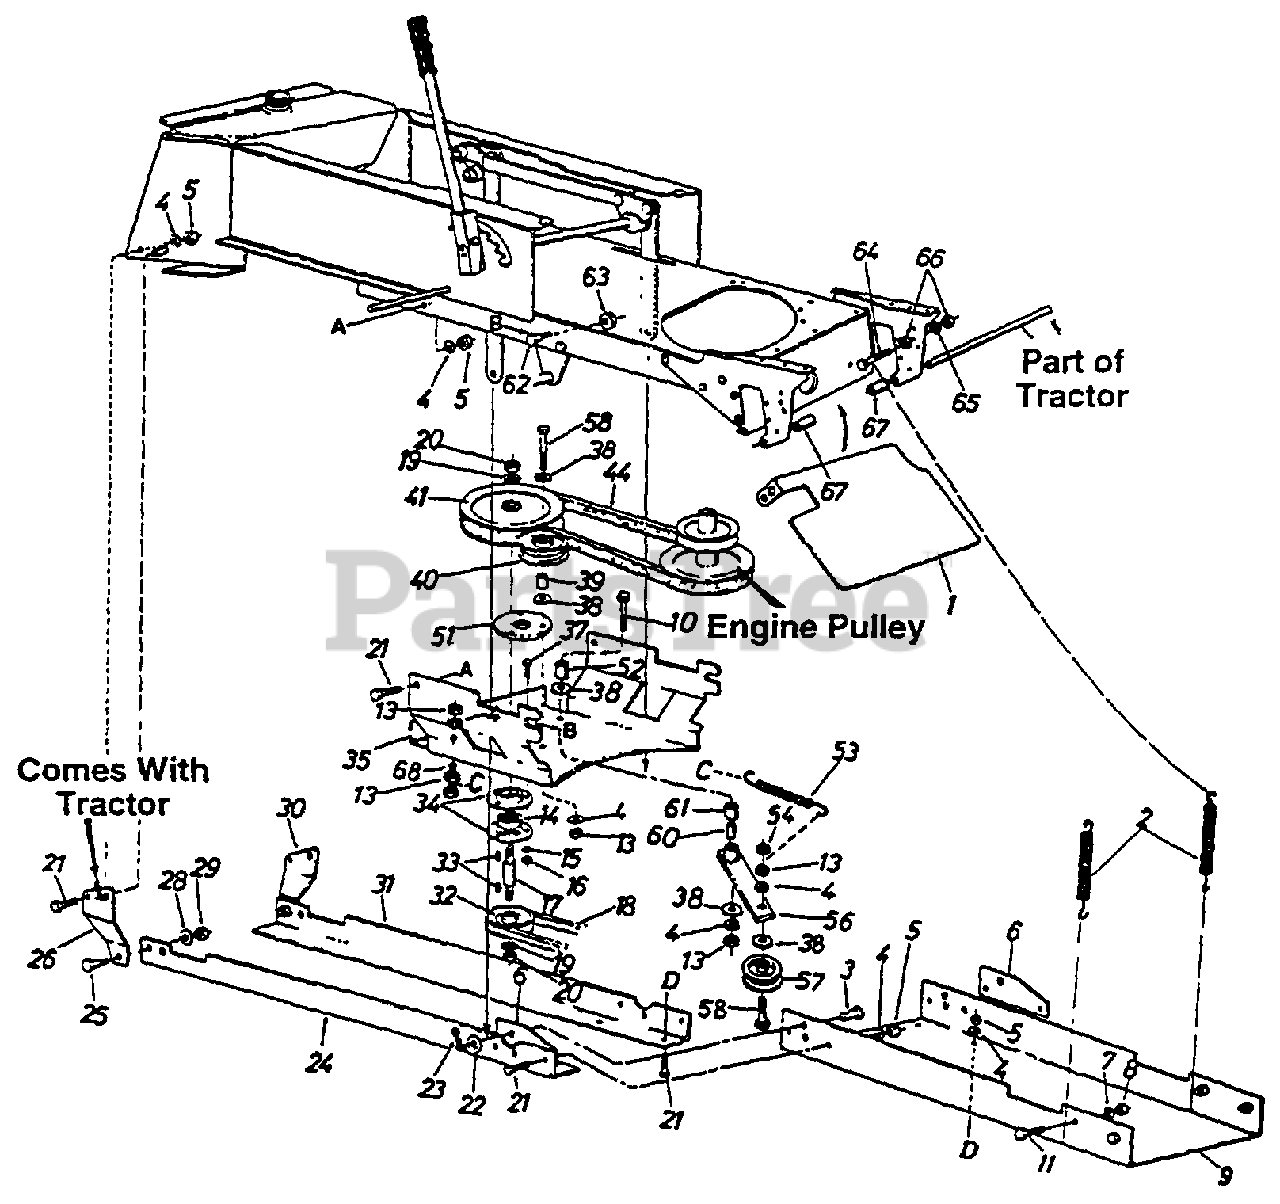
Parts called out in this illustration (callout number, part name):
3	Clevis Pin
4	L-Wash. 3/8" I.D.
5	Hex L-Nut 3/8-24 Thd.
6	Attaching Plate
7	L-Wash. 1/2" I.D.
8	Hex L-Nut 1/2-20 Thd.
11	Hex Bolt 1/2-20 x 1.25" Lg.
13	Hex Jam Nut 3/8-16 Thd.
14	Ball Bearing
15	L-Wash. 5/16" I.D.
16	Hex Nut 5/16-18 Thd.
17	Spindle
18	"V"-Belt
19	L-Wash. 5/8" I.D.
20	Hex Jam Nut 5/8-11 Thd.
21	Hex Bolt 3/8-24 x 1.00" Lg.
22	Flat Washer
23	Internal Cotter Pin
29	Hex Nut 7/16-14 Thd.
30	Rear Hanger Brkt.- L.H.
33	#6 Hi-Pro Key 3/16 x 5/8" Dia.
34	Bearing Housing
35	Supporting Bracket
37	Hex Sems Bolt 5/16-18 x 1"
38	Fl-Wash .38" I.D. x 1" O.D.
39	Spacer.38" I.D. x.62" 0 D.
40	Fl-Idler Pulley
41	Upper Drive Pulley
44	"V"-Belt
53	Extension Spring 4.75" Lg.
54	Hex I-Nut 3/8-16 Thd.
56	Idle Arm Ass'y.
57	Idler Pulley
58	Hex Bolt 3/8-16 x 2.25" Lg.
60	Spacer .377" I.D. x.83" Lg.
61	Spacer.38" I.D. x.565" Lg.
62	Shoulder Bolt .498" Dia.
63	Hex L-Nut 3/8-16 Thd.
64	Hex Bolt 1/4-28 x 1.50" Lg.
65	L-Wash. 1/4" I.D.
66	Hex Nut 1/4-28 Thd.
67	Spacer .63" I.D. x 1.75" Lg.
68	Hex Bolt 3/8-16 x 2" Lg.
